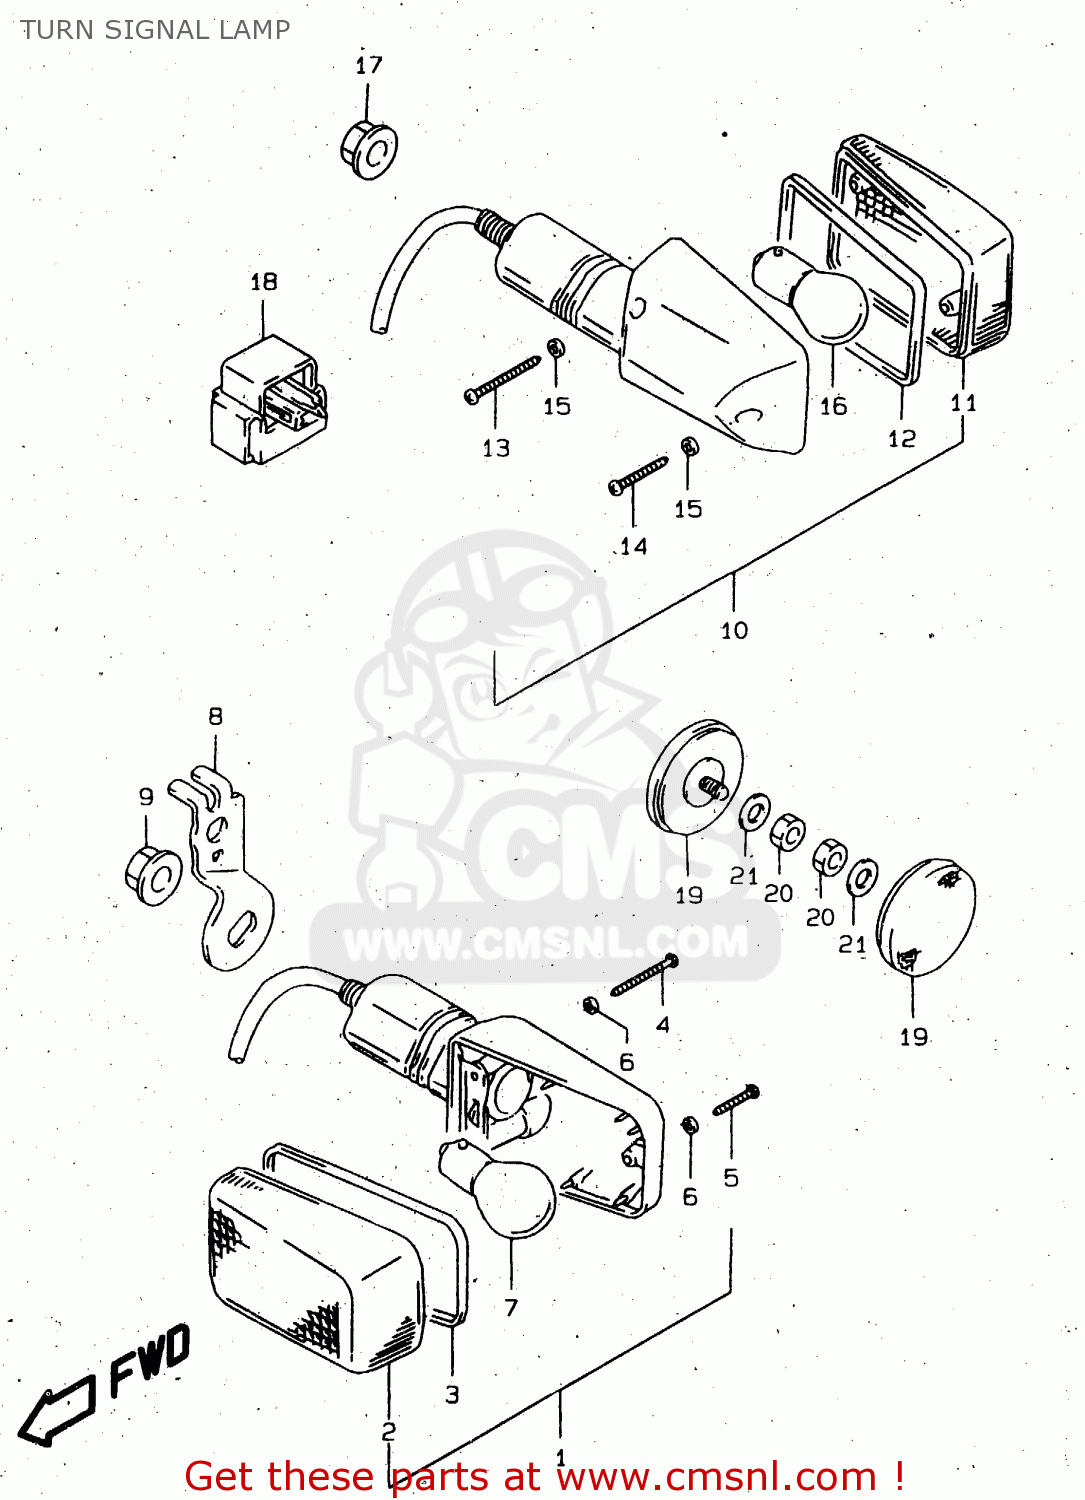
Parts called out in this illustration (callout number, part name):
1	LAMP ASSY,FR TURN SIGNAL
2	LENS
3	GASKET (NAS)
4	SCREW(3X30)
5	SCREW
6	GASKET (NAS)
7	BULB(12V21W)
8	BRACKET,FR TURNSIGNAL,R
9	NUT
10	LAMP ASSY,RR TURNSIGNAL,R
11	LENS
12	GASKET (NAS)
13	SCREW(3X30)
14	SCREW
15	GASKET (NAS)
16	BULB(12V21W)
17	NUT
18	RELAY ASSY
19	REFLECTOR,REFLEX
20	NUT
21	LOCK,WASHER
